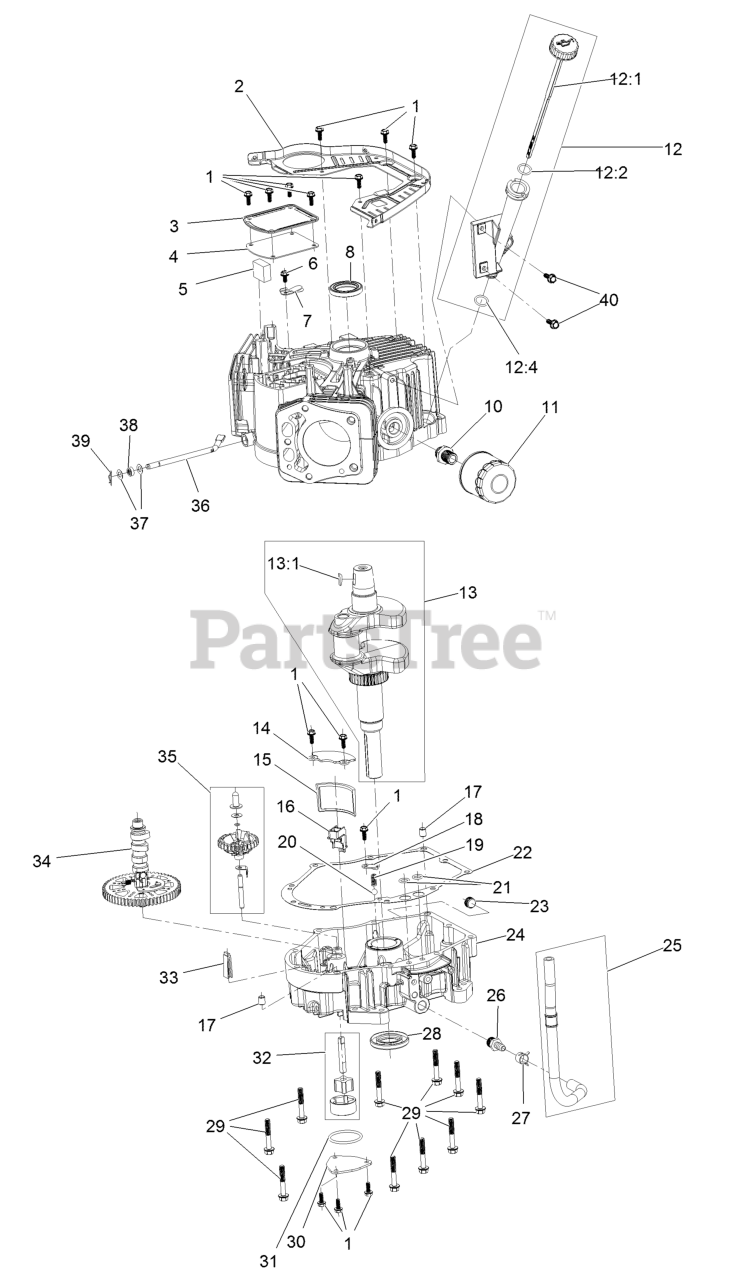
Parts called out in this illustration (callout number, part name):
1	Screw-HHF
3	Cover-Breather
4	Gasket-Breather
5	Filter-Breather
6	Screw-HHF
7	Valve-Breather
8	Seal-Oil
10	Adaptor-Filter, Oil
11	Filter-Oil
12	Oil Tube ASM
12:1	Dipstick
13	Crankshaft
13:1	Key-Woodruff
14	Cover-Screen, Oil
15	Screen-Oil
16	Retainer-Screen
17	Pin-Dowel
18	Plate-Retainer
20	Valve-Ball
22	Gasket-Cover, Crankcase
23	Plug-Drain
24	Cover-Crankcase
25	Oil Drain Hose ASM
26	Fitting-Hose
27	Clamp-Hose
29	Screw-HHF
30	Cover-Oil Pump
32	Oil Pump ASM
33	Deflector-Oil, Rubber
34	Camshaft
35	Governor ASM
36	Shaft-Governor
37	Washer-Plain
38	Seal-Oil
39	Pin-Hair
40	Screw-HHF
